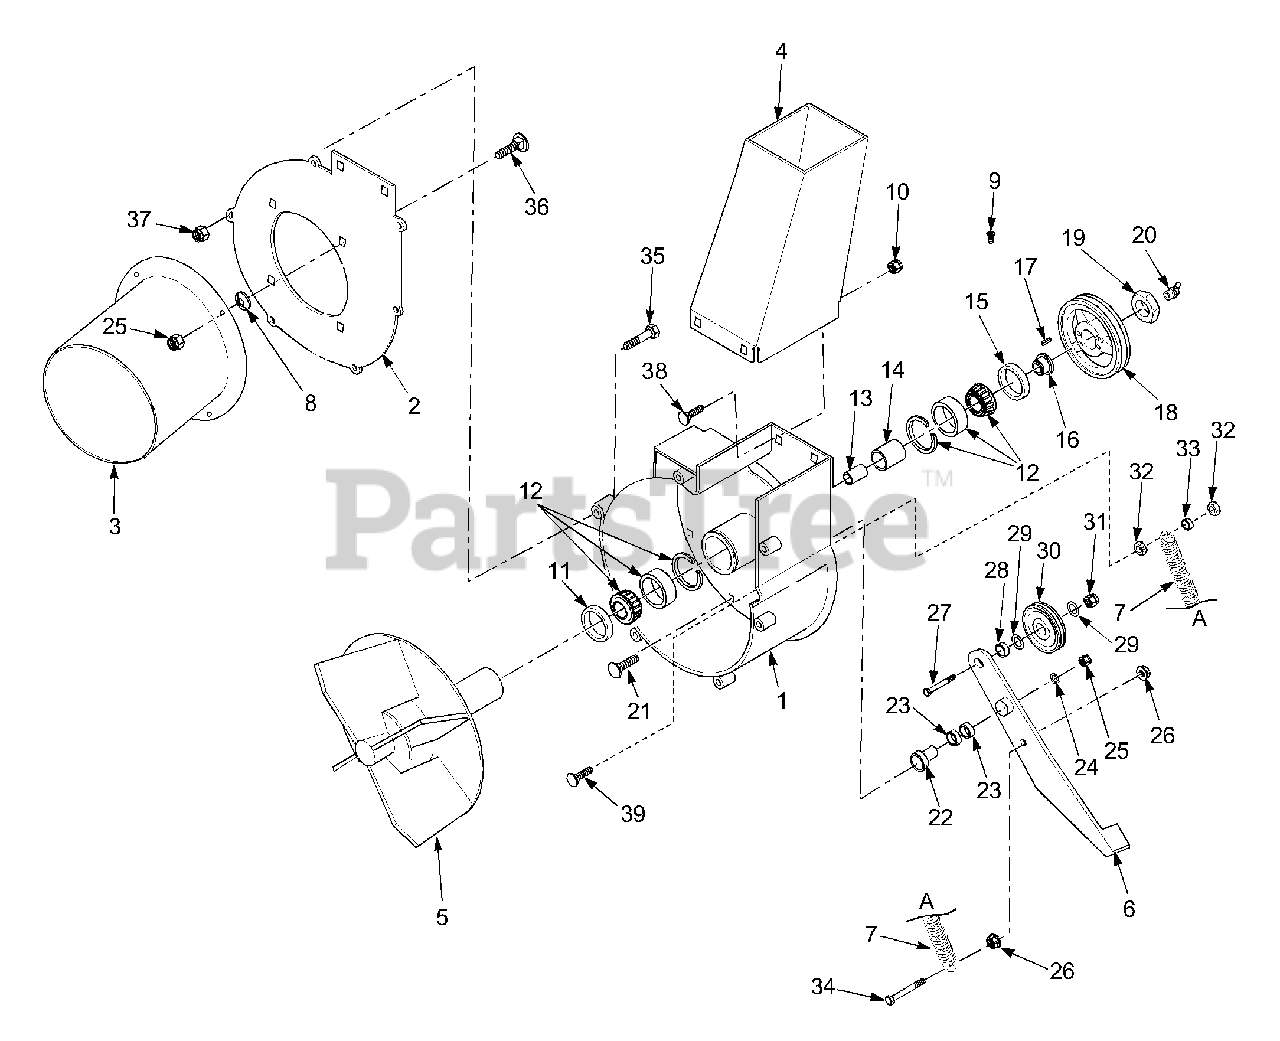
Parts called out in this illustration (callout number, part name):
1	Blower Housing, Rear
2	Blower Housing, Front
3	Inlet
4	Outlet
6	Idler Arm, Weldment
7	Spring
8	Push Nut, 3/8 Thread
9	Relief Fitting
10	Nut, Elastic Stop 1/4-20
11	Seal, 2.00 OD x 1.50 Bore
12	Bearing Assembly
13	Spacer, Inside
14	Spacer, Outside
15	Seal, 2.00 OD x 1.625 Bore
16	Bushing
17	Key, 1/4 x .874 Woodruff
18	Pulley, 5.25 OD
19	Nut, 1-1/16 - 18 LH Thread
20	Grease Fitting, 65 degree angle
21	Bolt, Carriage 3/8-16 x 2.5"
22	Idler Arm w/pivot
23	Bearing
24	Flatwasher 3/8"
25	Nut, Elastic Stop 3/8-16
26	Nut, Serr. Flng. 3/8-16
27	Bolt, HH 3/8-16 x 2.25"
28	Spacer
29	Flat Washer 3/8"
30	Pulley, 3.0" diameter
31	Nut, Elastic Stop 3/8-16
32	Nut, Serr. Flng. 3/8-16
33	Spacer
34	Bolt, HH 3/8-16 x 1.5"
35	Bolt, HH 5/16-18 x 1.5"
36	Bolt, Carriage 3/8-16 x 1.0
37	Nut, Elastic Stop 5/16-18
38	Bolt, Carriage 1/4-20 x 1.0
39	Bolt, Carriage 3/8-16 x 1-1/2"
